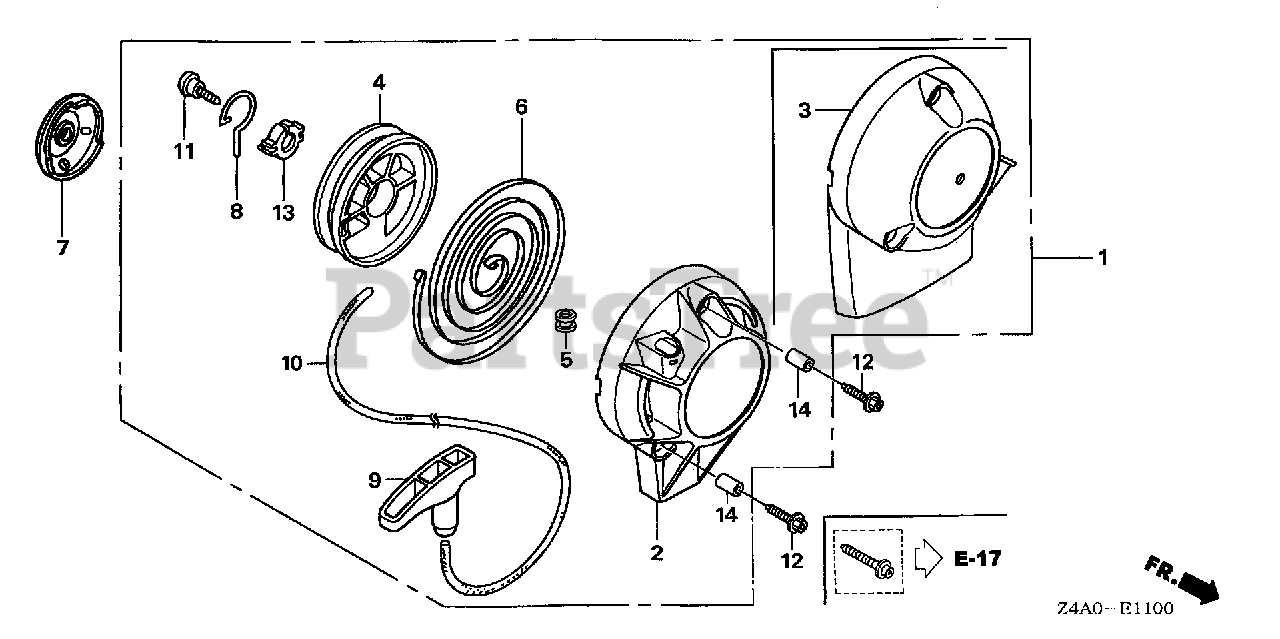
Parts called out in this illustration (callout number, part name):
1	STARTER ASSY., RECOIL
1	STARTER ASSY., RECOIL (FOR U.S.A.)
2	CASE, RECOIL STARTER
4	REEL, RECOIL STARTER
5	GUIDE, ROPE
6	SPRING, RECOIL STARTER
7	PULLEY, RECOIL STARTER
9	KNOB, RECOIL STARTER
10	ROPE, RECOIL STARTER
11	SCREW, SETTING
12	BOLT, SOCKET (5X16)
14	COLLAR A, HEAD COVER
